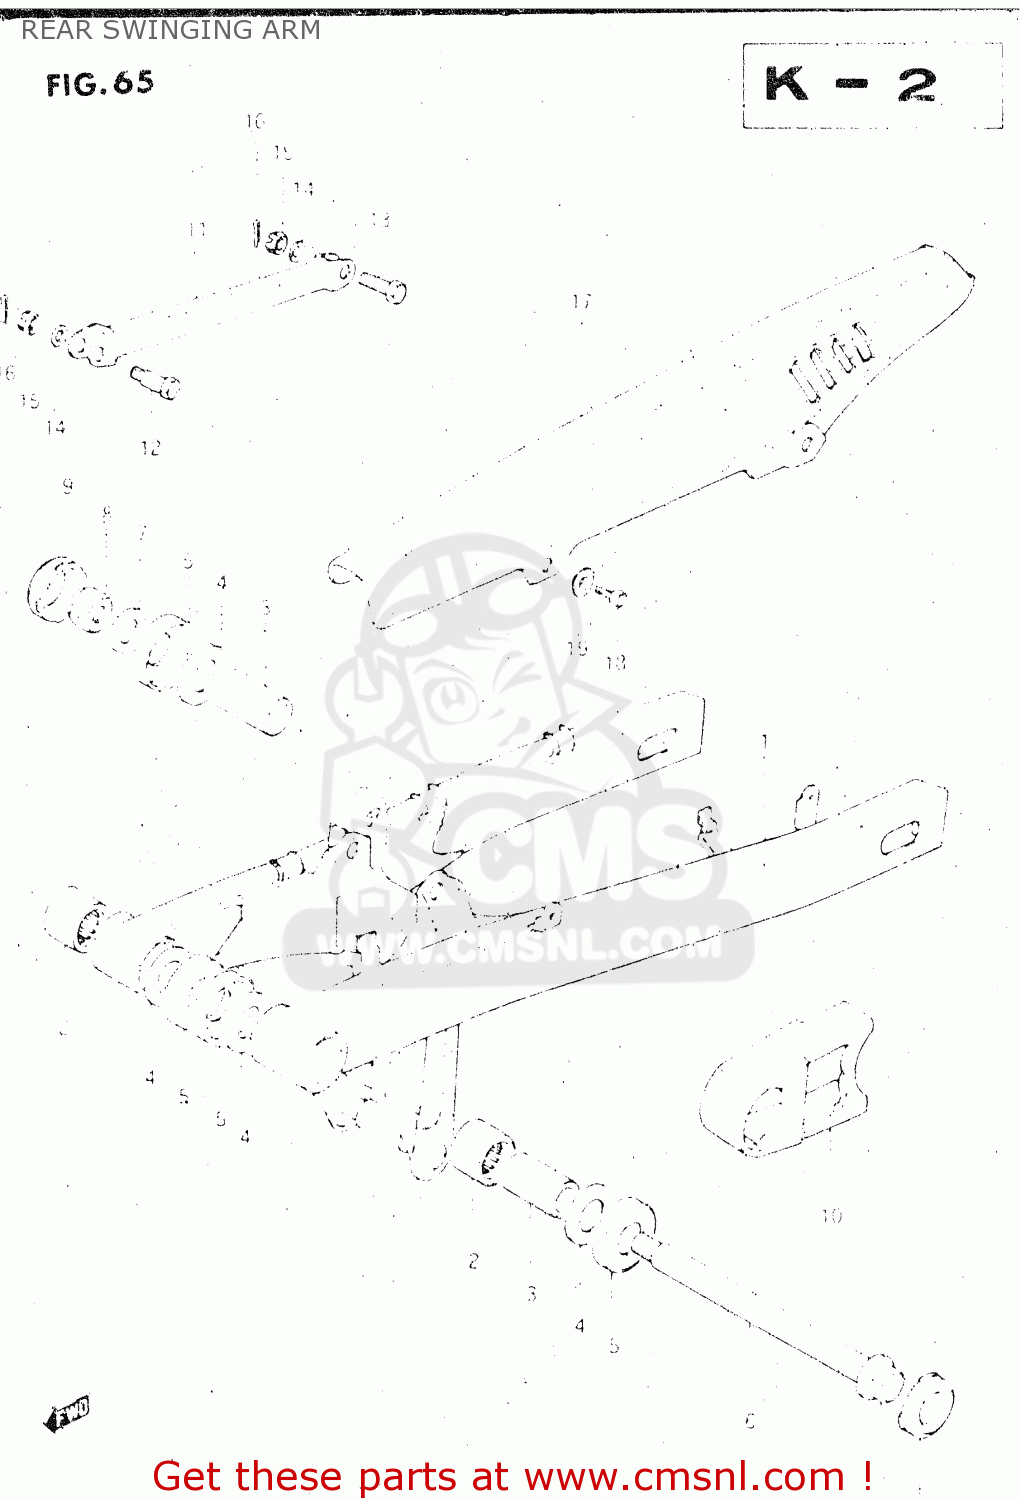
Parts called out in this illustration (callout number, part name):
1	ARM,REAR SWING
2	BEARING(25X33X30)
3	SPACER,RR SWGARM PIVOT
4	WASHER
5	COVER,RR SWGARM DUST SEAL
6	SHAFT,REAR SWING ARM
7	WASHER
8	NUT
9	CAP,SWINGINGARM PIVOT
10	BUFFER,DEFENSE
11	TORQUE LINK,REAR
12	BOLT
13	BOLT
14	WASHER
15	NUT
16	PIN 20X20
17	CASE,CHAIN
18	BOLT
19	WASHER
